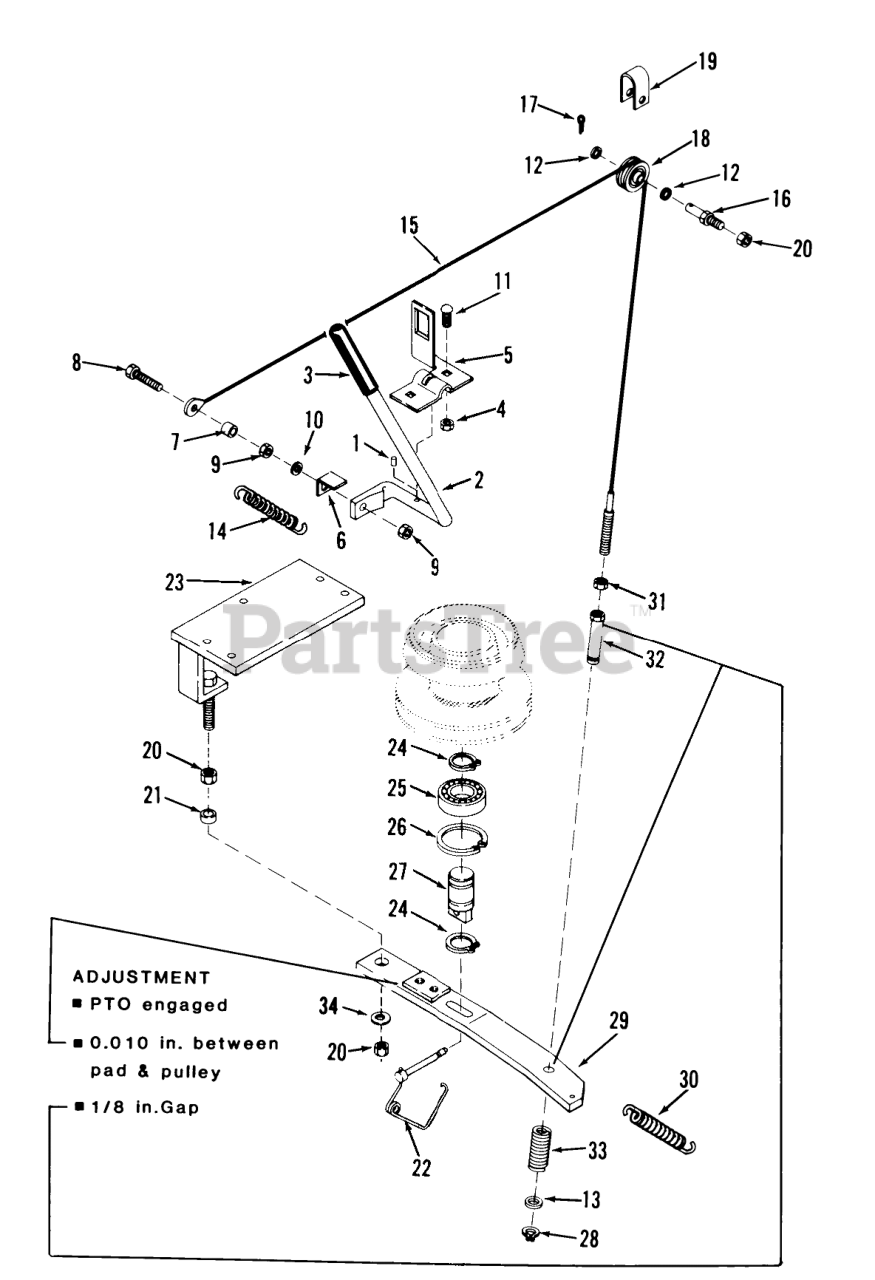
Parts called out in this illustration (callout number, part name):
1	SPIROL PIN
2	PT0 Clutch Lever
3	GRIP
4	Nut
5	Clamp
6	Angle
7	Spacer
8	Bolt 1/4-20 X 1 1/2
9	Nut
11	Bolt Carnage
12	Washer
13	Washer
14	SPRING-EXTENSION
15	ASSY-CABLE
17	Cotter Pin
18	ROLLER-CABLE
19	STRAP-CABLE
20	Nut
21	SPACER-CLUTCH BAR
22	Pin
23	Clutch Plate
24	RING-SNAP, EXTERNAL
25	BEARING-BALL
26	Ring-Snap
27	SHAFT-CLUTCH HSG
28	Retaining Ring
29	Clutch Brake Bracket
30	Spring
31	Jam Nut 5/16-18
32	TUBE-CLUTCH SPACER
33	SPRING-CLUTCH
34	Washer
